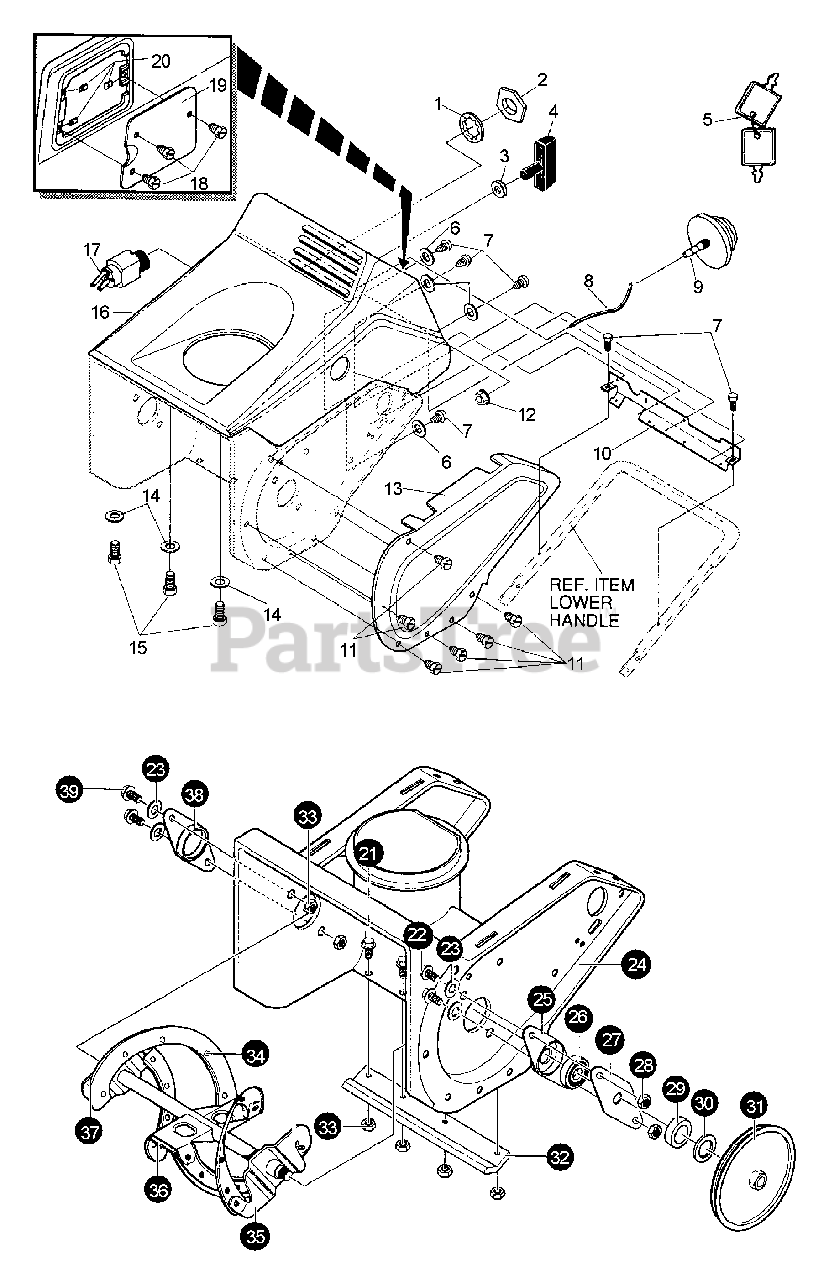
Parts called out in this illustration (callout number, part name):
1	WASHER
2	NUT
3	GROMMET & WASHER, ROPE GUIDE
4	KNOB, TEE
5	KEYS & RING ASSY
6	WASHER
7	SCREW - 10-24 X .63"
8	HOSE, PRIM 5.75 LONG
9	PRIMER, ENGINE 2CY
10	BRACKET, SHROUD MNTG
11	SCREW - 10-24 X 3/8"
12	NUT - 1/4-20 -- KEPS
13	COVER, BELT
14	WASHER
15	SCREW - 10-14 X .63"
16	COVER - TOP
17	SWITCH, IGNITION
18	SCREW - 10-16 X .75"
19	DOOR, ACCESS
20	NUT
21	SCREW - 1/4-20 X 5/8"
22	SCREW - 1/4-20 X .75"
23	WASHER
24	AUGER INTAKE ASSY - 21"
25	RETAINER, BEARING
26	BEARING, BALL - 6203
27	RETAINER, BEARING
28	NUT - 1/4-20
29	SPACER, SLEEVE .640 X .88 X .15
30	WASHER - .640 X 1.25 X .06
31	PULLEY, POLYV 6" OD 10 RIB
32	BLADE, SCRAPER
33	LOCKNUT - 1/4-20
34	RIVET - .250 X .5"
35	AUGER ASSY - 21"
36	CENTER, AUGER BLADE
37	AUGER, BLADE STRIP
38	BEARING, FLANGE
39	SCREW - 1/4-20 X 7/8"
